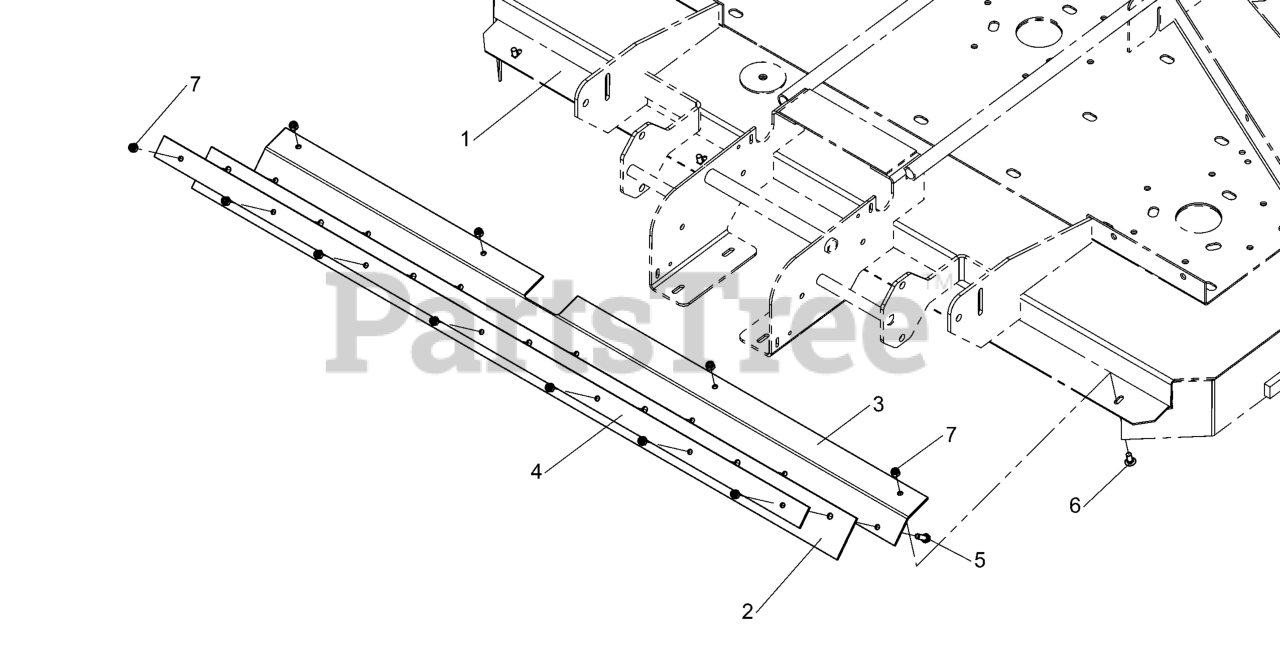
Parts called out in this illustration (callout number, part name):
1	MOWER DECK
2	RUBBER DEFLECTOR
3	DEFLECTOR PLATE
4	RETAINING PLATE
5	BOLT, 5/16-18 X 1"
6	CARRIAGE BOLT, 5/16-18 X 3/4
7	NUT 5/16-18 Hex Nylon Lock
